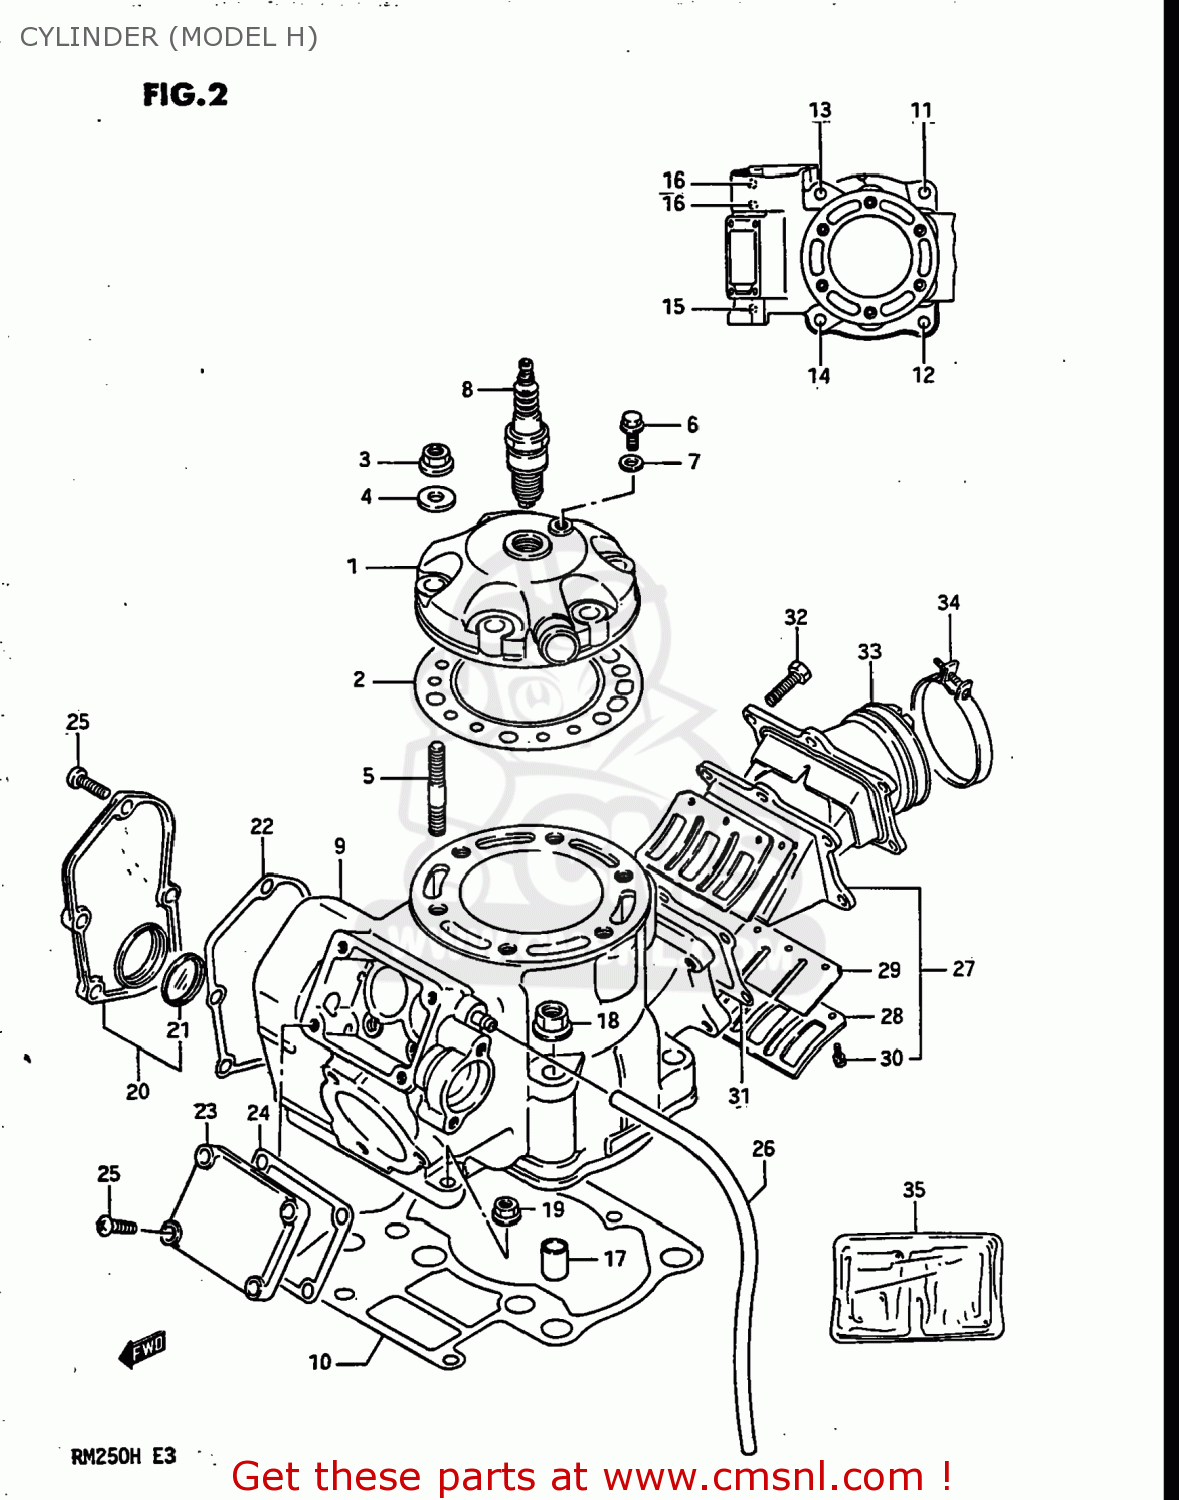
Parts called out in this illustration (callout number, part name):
1	HEAD,CYLINDER
2	GASKET,CYLINDER HEAD (MCA)
3	NUT
4	WASHER
5	BOLT,STUD
6	UNION
7	GASKET(6.2X11X1).2 (NAS)
8	PLUG,SPARK(NGK B-8EN)
9	CYLINDER
10	GASKET,CYLINDER (MCA)
11	STUD BOLT (L:40)
12	STUD BOLT (10X50)
13	STUD
14	STUD BOLT (10X90)
15	STUD 6X25
16	STUD BOLT
17	PIN
18	NUT
19	NUT
20	COVER COMP,CYLINDER
21	LENS,CYLINDER COVER
22	GASKET,CYLINDER COVER (MCA)
23	COVER,CYLINDER NO.2
24	GASKET,CYLINDER COVER NO.2 (MCA)
25	SCREW
26	HOSE
27	VALVE ASSEMBLY,REED
28	STOPPER,REED VALVE
29	VALVE,REED
30	SCREW,REED VALVE
31	GASKET,REED VALVE (MCA)
32	BOLT
33	PIPE,INTAKE
34	CLAMP
35	GASKET SET (MCA)
